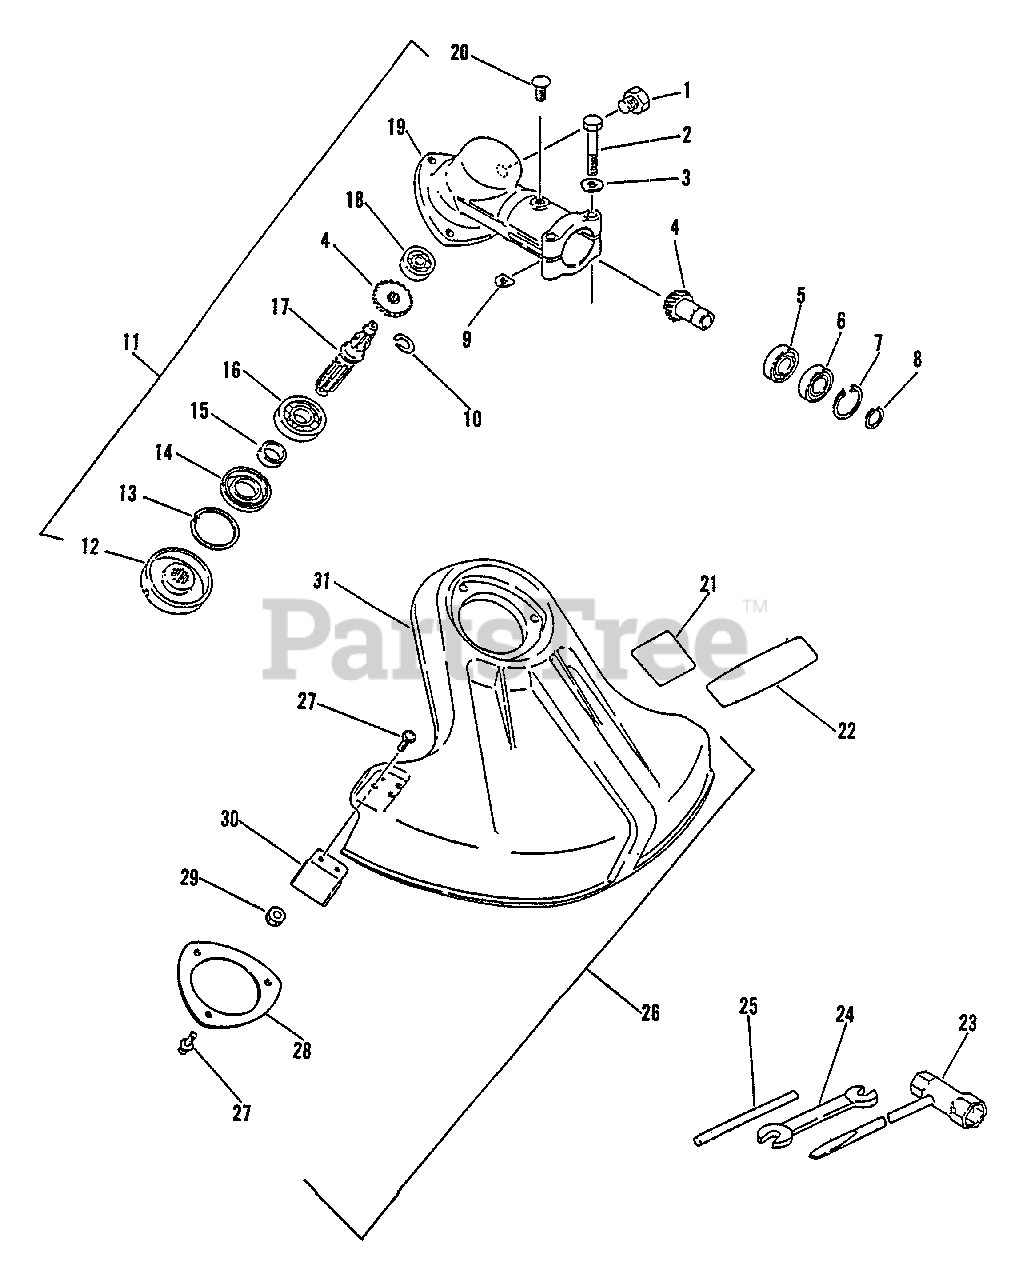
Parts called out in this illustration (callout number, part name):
1	BOLT 8×8 SP
2	BOLT 5×35 SP
3	WASHER, FLAT 5.5×10×0.8
4	GEAR SET
5	BEARING, BALL 6900
6	BEARING, BALL 6900Z
7	RING, SNAP Ø22
8	RING, SNAP Ø12
10	RING, SNAP Ø10
11	GEAR CASE ASSY
12	PLATE, ADAPTOR - UPPER
13	RING, SNAP Ø32
14	SEAL, OIL 22
15	SPACER 11.8×15×9
16	BEARING, BALL 6201
17	SHAFT, GEAR
18	BEARING, BALL 609
19	HOUSING, GEAR CASE
20	SCREW 5×10
21	LABEL, CAUTION
22	LABEL, ECHO
23	T-WRENCH
24	SPANNER 8×10
25	TOOL, LOCKING 5×120 MM
26	DEBRIS SHIELD ASSY
27	SCREW 5×16
28	BRACKET, SHIELD
29	NUT M5
30	CUTTER, LINE
31	SHIELD, DEBRIS
